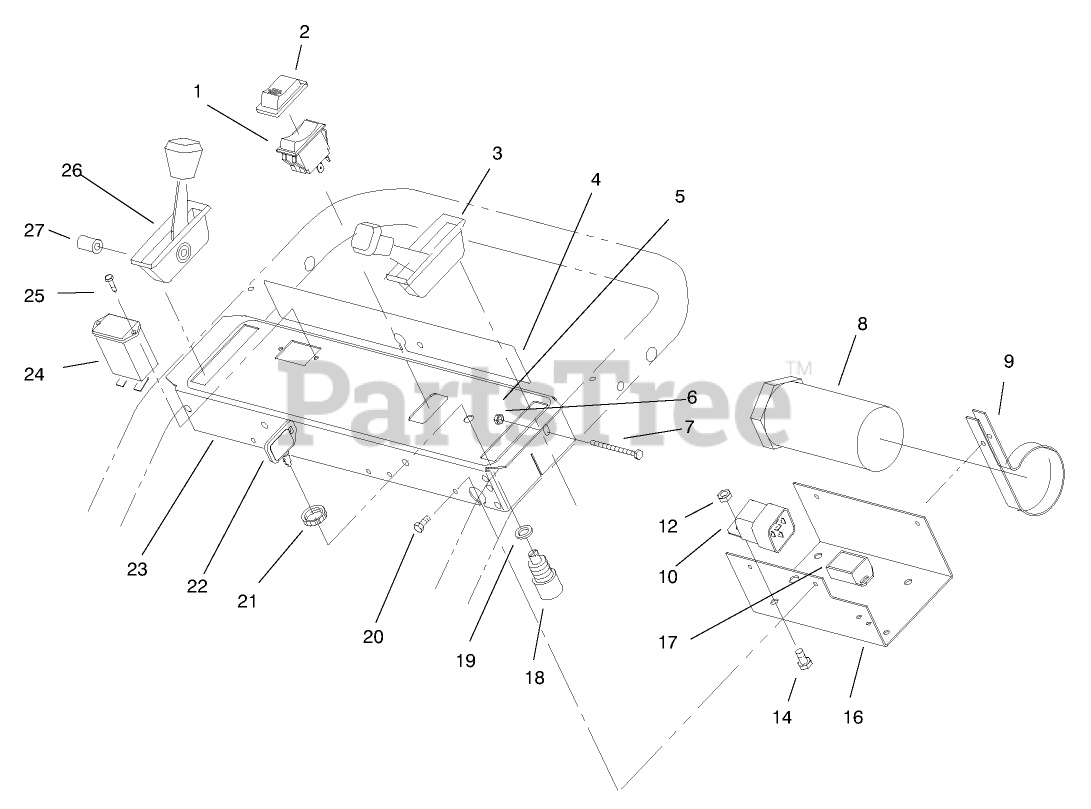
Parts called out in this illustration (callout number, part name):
1	SWITCH
2	BOOT-SWITCH
3	CONTROL - THROTTLE
4	DECAL-WARNING
5	DECAL - CONTROL PANEL
6	NUT-LOCK, NI
7	SCREW-SHH
8	TUBE-MANUAL
9	CLAMP-R
10	RELAY
12	NUT-LOCK, NI
14	SCREW-HH
16	PANEL-BOTTOM
17	MODULE
18	SWITCH-ON / OFF
19	WASHER-TOOTH, INTERNAL
20	SCREW-HWHTF
21	NUT-HH
22	KEY-IGNITION
23	PANEL-CONTROL
26	CONTROL - CHOKE
27	SPACER
